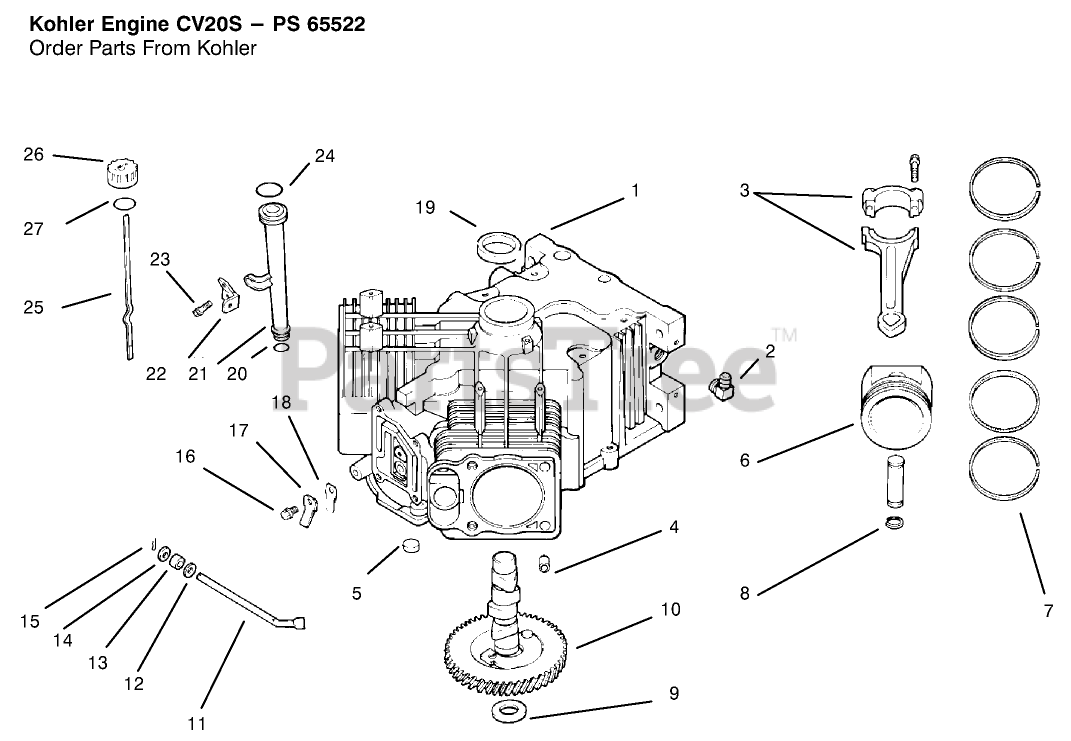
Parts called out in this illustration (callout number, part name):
1	Miniblock
2	Fitting
3	Connecting Rod STD
4	Pin-Dowel
5	Plug
6	Set-Piston w/Ring (Incl. Ref. #7-8)
7	Ring Set(Std.)
8	Retainer-Piston Pin
9	Shim-Camshaft
10	Camshaft
11	Shaft-Governor Cross
12	Washer
13	Seal-Cross Shaft
14	Washer
15	Pin-Hitch
16	Screw
17	Retainer-Reed
18	Beed-Breather
19	Seal-Oil
20	"O"Ring
21	Tube-Oil Fill
22	Bracket-Oil Tube
23	Screw
24	"O"Ring
25	Dipstick Assembly (Incl. Ref. # 26-27)
26	Kit-Fill Cap (Incl. Ref. # 27)
27	"O"Ring
